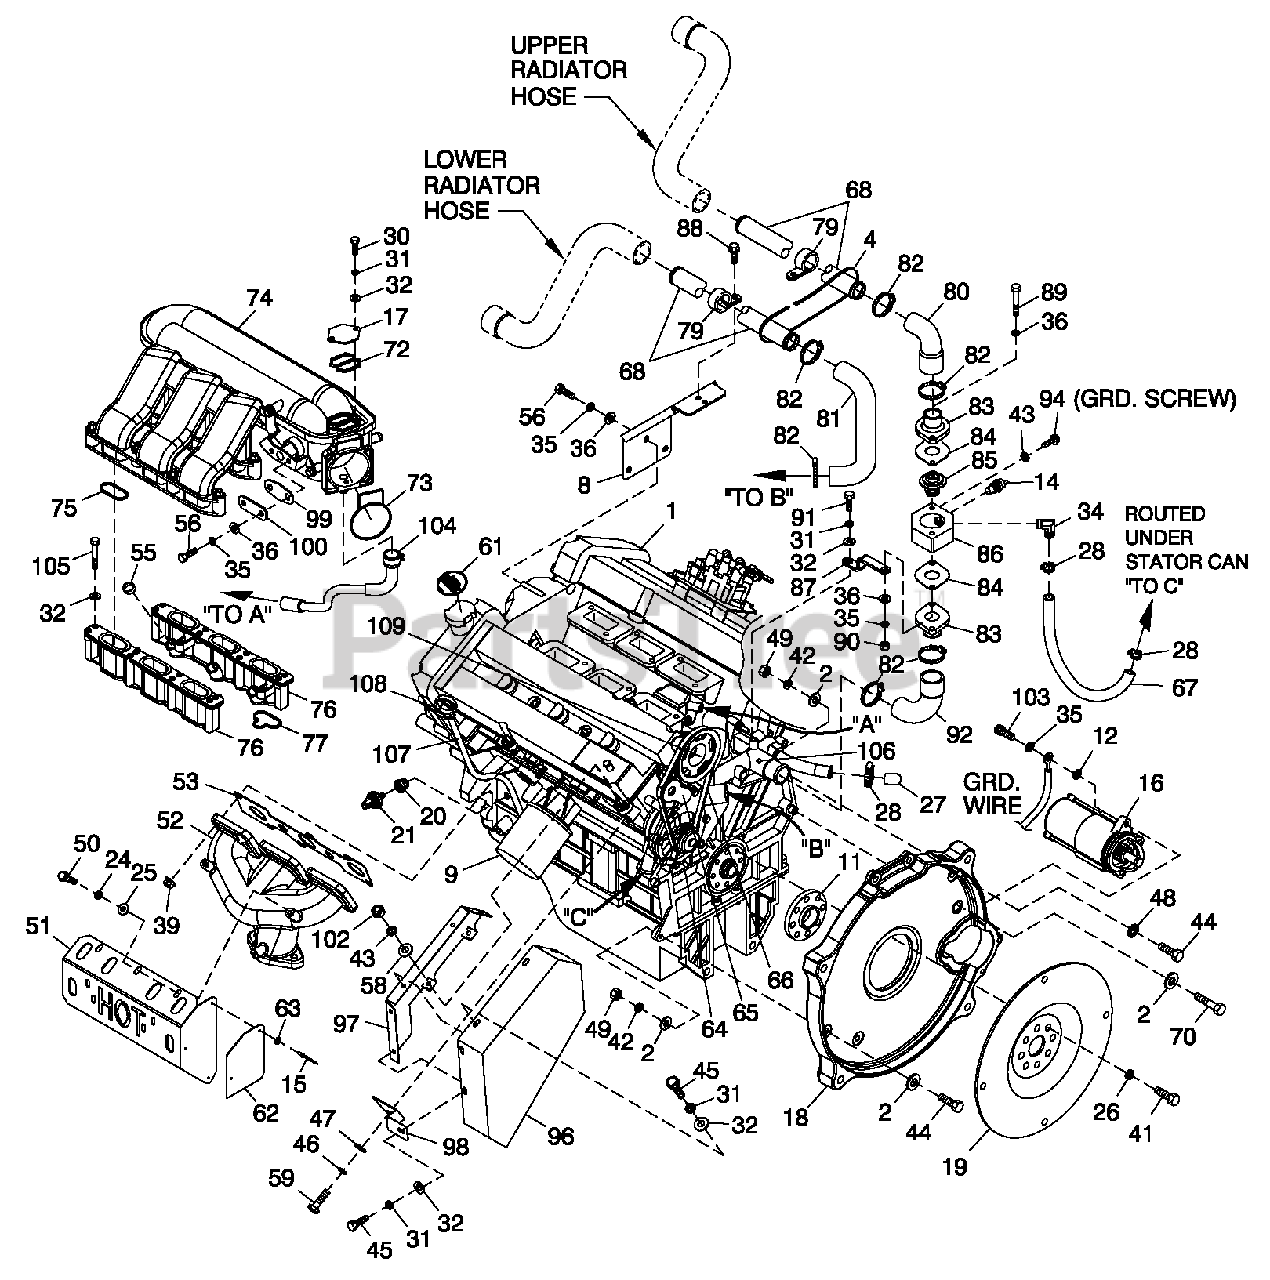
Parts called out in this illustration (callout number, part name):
1	ENGINE FWD MAKE
2	WASHER FLAT 3/8-M10 ZINC
3	ADAPTER CRANKSHAFT
4	TIE WRAP UL 17.7 X .35 BLK HT
5	BRACKET DC ALTERNATOR
6	ALTERNATOR DC W/OUT PULLEY
7	PULLEY 80 OD DC ALTERNATOR
8	SUPPORT COOLANT TUBE
9	OIL FILTER
10	BELT SERPENTINE 28.92"
11	SPACER FLEX PLATE
12	WASHER SHAKEPROOF EXT 5/16 STL
13	SPAC ER.19 X .31 X .50 PL
14	SWITCH HI-TEMP 245D X 3/8 NPT
15	RIVET POP .125 X .400 AL
16	STARTER 12 VOLT
17	COVER IAC ACTUATOR
18	ADAPTER ENGINE
19	FLEX PLATE 2 POLE
20	BSHG RDCR HEX 3/8 TO 1/8 GALV
21	SWITCH OIL PRESSURE 10 PSI 2 POL
22	CLAMP HOSE .38-.87
23	HOSE DRAIN ASSY 28"
24	WASHER LOCK 1/4-M6SS
25	WASHER FLAT 1/4 SS
26	WASHER FLAT .45X1.00
27	CAP ANTIFREEZE RUBBER
28	CLAMP HOSE #10.56-1.06
29	BARBED STR 3/8 NPT X 3/8
30	SCREW HHC M6-1.0X 16 G8.8
31	WASHER LOCK M6-1/4
32	WASHER FLAT 1/4-M6 ZINC
33	ADAPTER M12-1.75X 3/8 NPT
34	BARBED EL 90 1/2 NPT X 3/4 HOSE
35	WASHER LOCK M8-5/16
36	WASHER FLAT 5/16-M8 ZINC
37	WASHER NYLON .50 X .87 X .06
38	SCREW HHC M8-1.25X25G8.8
39	NUT HEX FLWHIZ M8-1.25
40	COIL IGNITION
41	SCREW HHC M10-1.0X25G10.9
42	WASHER LOCK M10
43	WASHER LOCK M5
44	SCREW HHC M10-1.5 X 45 G8.8 FT
45	SCREW HHC M6-1.0X 12 G8.8
46	WASHER LOCK M12
47	WASHER FLAT M12
48	WASHER SHAKEPROOF EXT 7/16 STL
49	NUT HEX M10-1.5 G8YEL CHR
50	SCREW HHC 1/4-20X1/2 SS
51	HEAT SHIELD 260X80 HOT
52	MANIFOLD EXHAUST LH
53	GASKET EXHAUST
55	PLUG EXPANSION 14 OD
56	SCREW HHC M8-1.25X20 G8.8
57	SPACER ALTERNATOR
58	WASHER FLAT M5
59	SCREW HHC M12-1.75 X 20 G8.8
60	WIRES, SPARK PLUG
61	DECAL REFER TO OWNERS MANUAL
62	REFLECTIVE HEAT SHIELD
63	WASHER FLAT #6 ZINC
64	PUMP WATER
65	TENSIONER WATER PUMP
66	BELT WATER PUMP
67	HOSE COOL 3/4 ID 20R3 (51.5" LG)
68	TUBE UPPER COOLANT
69	SCREW HHC M8-1.25X50G8.8
70	SCREW HHC M10-1.5X60G8.8
71	SPACER DC ALTERNATOR PULLEY
72	GASKET IDLE AIR CONTRL ACT CVR
73	GASKET INTAKE ADAPTER
74	MANIFOLD INTAKE UPPER
75	GASKET INTAKE MANIFOLD UPPER
76	MANIFOLD INTAKE LOWER
77	GASKET INTAKE LOWER
78	MANIFOLD EXHAUST RH
79	CLAMP VINYL 1.5 X .281 Z
80	HOSE UPPR RAD REAR
81	HOSE, LOWR RAD REAR
82	CLAMP HOSE #28 1.32-2.25
83	ADAPTER THERMOSTAT
84	GASKET THERMOSTAT
85	THERMOSTAT 195 DEG
86	MACHINING-THERMOSTAT ADPTR
87	BRACKET,THERMOSTAT
88	SCREW THF M6-1X16 N WA Z/JS
89	SCREW HHC M8-1.25X80 G8.8
90	NUT HEX M8-1.25 G8 CLEAR ZINC
91	SCREW HHC M6-1.0X 25 G8.8
92	HOSE UPPR RAD REAR
93	SCREW HHCM10-1.5X50 G8.8
94	SCREW HHTT M5-0.8X 10 BP
95	SCREW HHC M5-0.8X 25 G8.8
96	GUARD WATER PUMP REAR
97	GUARD WATER PUMP FRNT
98	BRKT WATERPUMP GUARD
99	EGRGASKET
100	COVEREGR
101	BRACKET COIL
102	NUT HEX M5-0.8 G8 CLEAR ZINC
103	SCREW SHC M8-1.25 X 30 G12.9
104	ASSEMBLY HOSE PCV VALVE
105	SCREW HHC M6-1.0X 80 G8.8
106	WATER TUBE ASSY 3.0L G3 FWD
107	DIPSTICK TUBE
109	ACCESSORY DRIVE PULLEY
